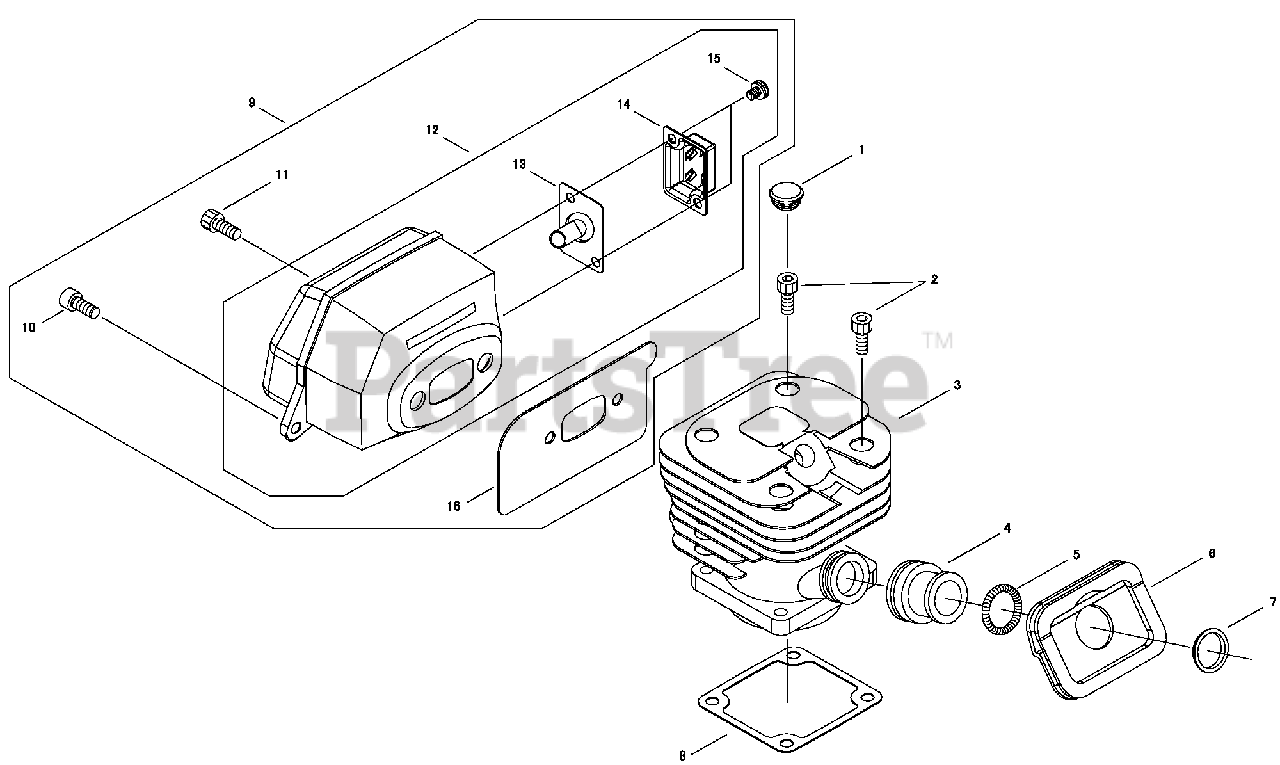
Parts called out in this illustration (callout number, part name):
1	PLUG
2	BOLT
3	CYLINDER
4	SEAL
5	SPRING
6	SEAL
7	SLEEVE
8	GASKET, CYLINDER
9	MUFFLER ASSY
10	BOLT
11	BOLT
12	MUFFLER SUB ASSY
13	SCREEN, SPARK ARRESTOR
14	GUIDE, EXHAUST
15	SCREW - 4X6
16	GASKET, EXHAUST
